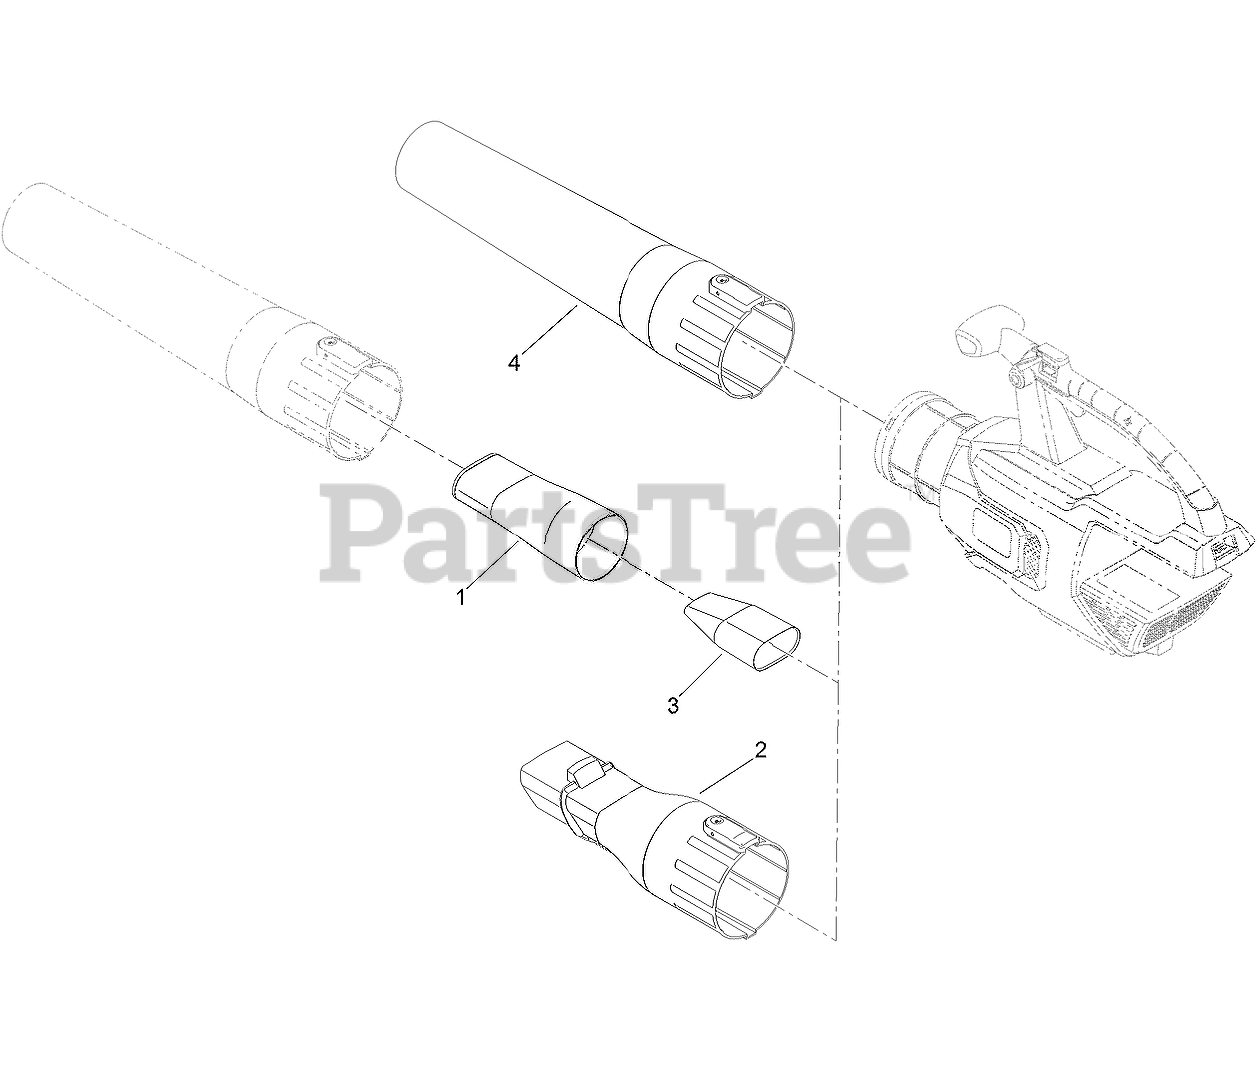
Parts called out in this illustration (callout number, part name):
1	ADAPTER-OSCILLATOR, MPH
2	ADAPTER-CLEANER, GUTTER
3	ADAPTER-INSERT, MPH
4	TUBE-BLOWER
